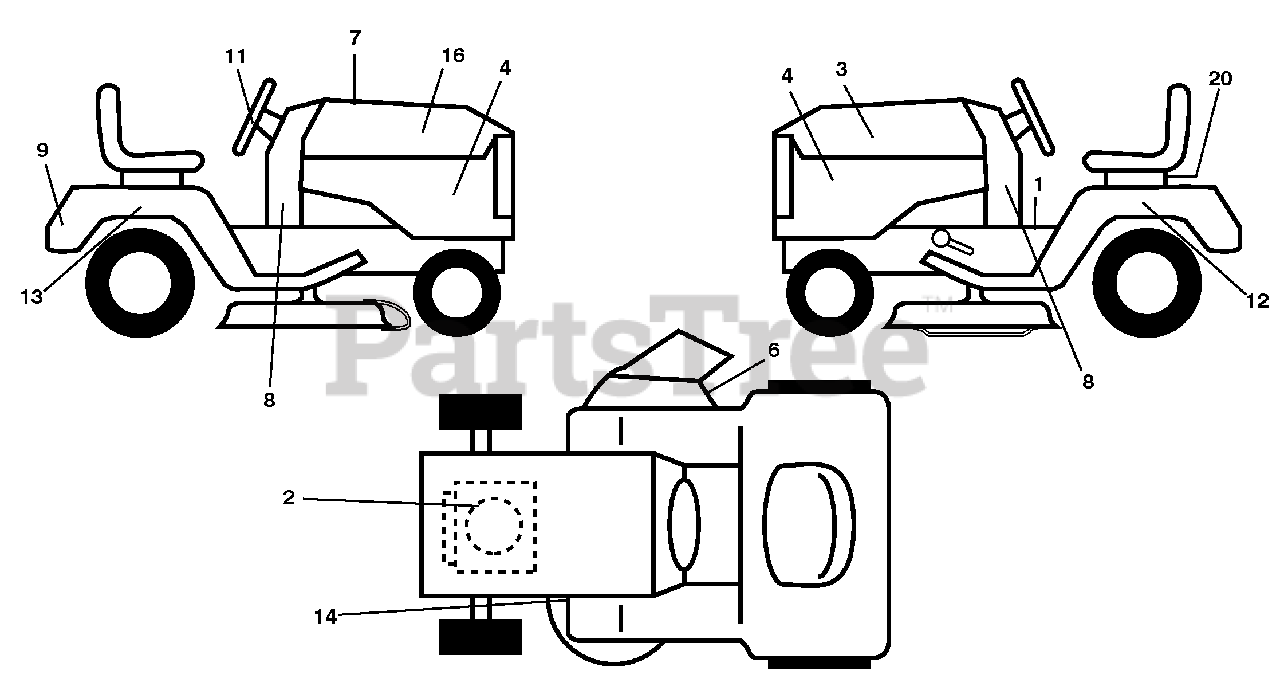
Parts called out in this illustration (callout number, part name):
1	Decal Fender Warning
2	Decal Engine H.P.
3	Decal Hood LH
4	Decal Side Panel
6	Decal Warning, Keep Hand Away
7	Decal Replacement Parts
8	Decal LWRDASH
9	Decal Fender Logo
11	Decal Ins Strg Whl
12	Decal Fender SD RH
13	Decal Fender SD LH
14	Decal V-Belt Schematic
16	Decal Hood RH
20	Decal Bat Dan/Psn
20	Decal Warning Spark Arrestor
20	Pad Footrest LH
20	Pad Footrest RH
20	Decal Bypass
20	Manual Operator's E&F
20	Manual Parts
